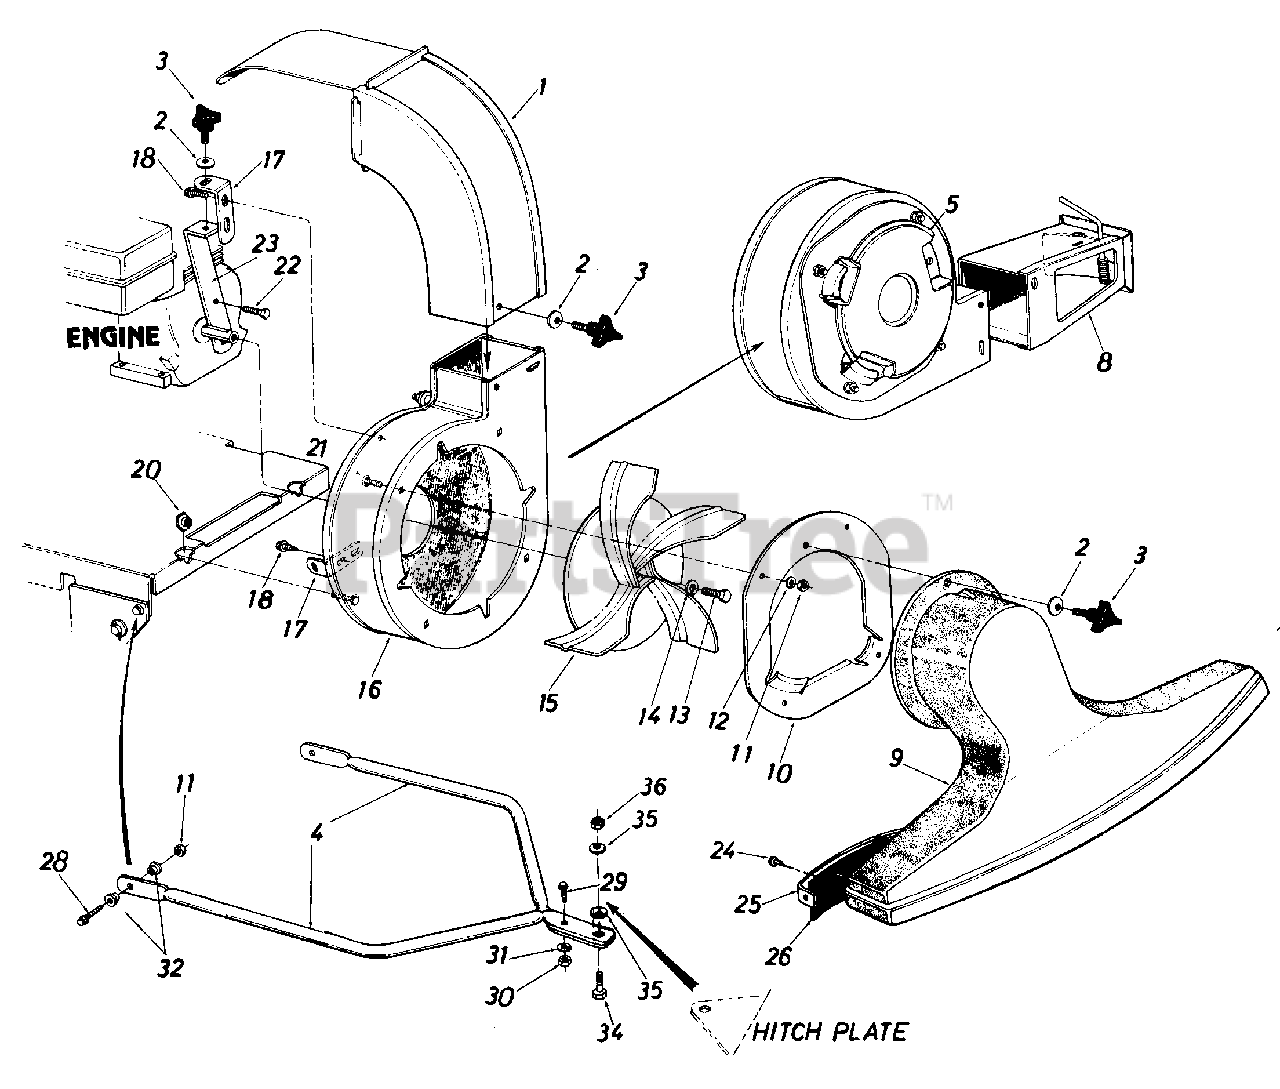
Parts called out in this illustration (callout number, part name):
3	3-Arm Thumb Scr. 5/16-18 x .75" Lg.
10	Nozzle Plate Ass'y.
11	Hex Nut 5/16-18 Thd.*
12	L.-Wash. 5/16" I.D.
13	Hex Bolt 3/8-24 x 1.25" Lg.*
14	L.-Wash. 3/8" I.D. H.D.
15	Air Vane Plate Ass'y.
20	Hex Shoulder Nut .50 I.D.
21	Carriage Bolt 5/16-28 x .62" 4.*
22	Hex Locking Bolt 5/16-24 x .75" Lg.
28	Hex Bolt 5/16-18 x 1.00" Lg.*
29	Truss Mach. Scr. 1/4-20 x .75" Lg.*
30	Hex Nut 1/4-20 Thd.*
31	L.-Wash. 1/4" I.D.*
32	Shoulder Spacer
34	Shld. Bolt .496 Dia.
35	Belleville Wash. .39 I.D. x 1.12 O.D.
36	Hex Jam L-Nut 3/8-26 Thd.
